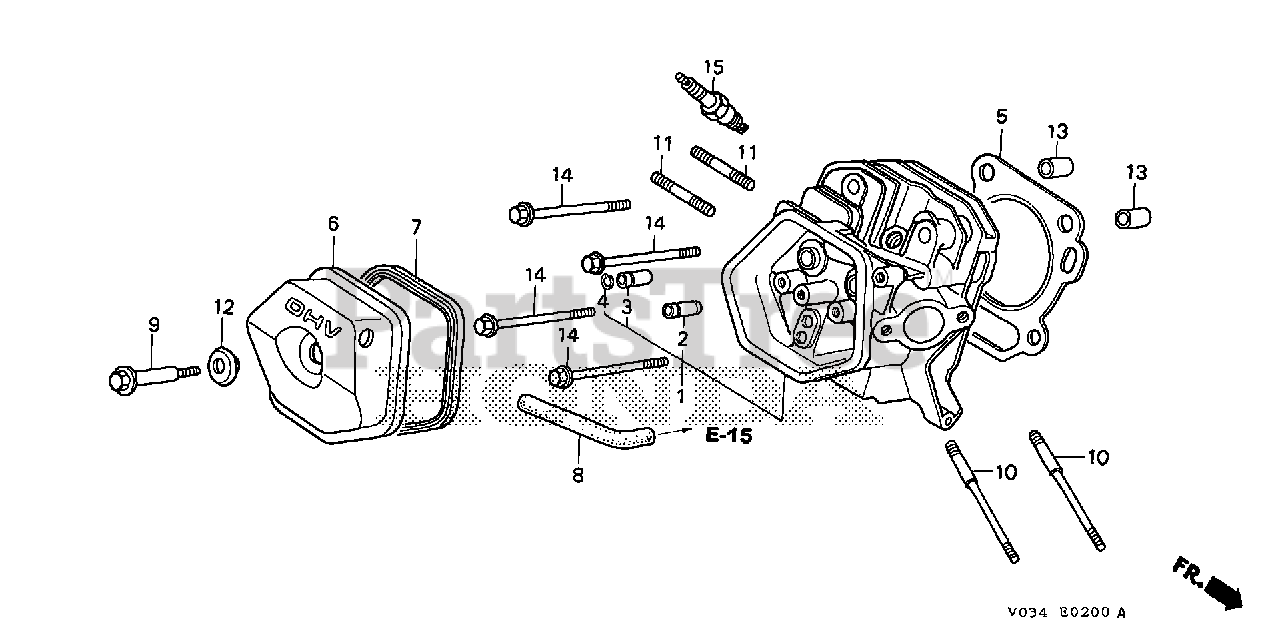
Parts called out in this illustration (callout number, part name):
1	CYLINDER HEAD
2	GUIDE, VALVE (OVER SIZE)
3	GUIDE, EX. VALVE (OVER SIZE)
4	CLIP, VALVE GUIDE
5	GASKET, CYLINDER HEAD
6	COVER, HEAD
7	GASKET, HEAD COVER
8	TUBE, BREATHER
9	BOLT, HEAD COVER
10	BOLT, STUD (8X131.5)
10	BOLT, STUD (8X134.5)
11	BOLT, STUD (8X32)
12	WASHER, HEAD COVER
13	PIN, DOWEL (12X20)
14	BOLT, FLANGE (10X80)
15	SPARK PLUG (BPR5ES) (NGK)
15	SPARK PLUG (W16EPR-U) (DENSO)
